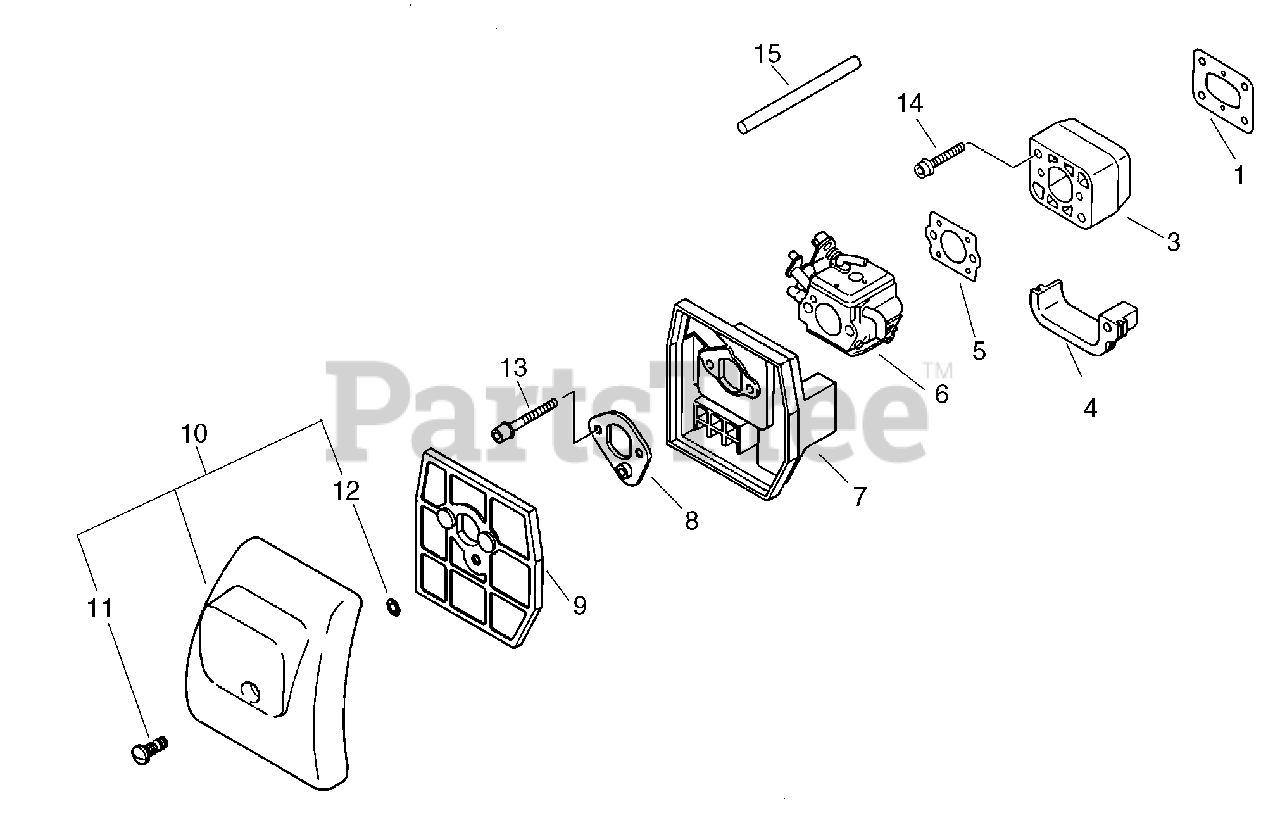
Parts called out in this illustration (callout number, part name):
1	GASKET, INTAKE
3	INSULATOR
5	GASKET, INTAKE
6	CARBURETOR CLS-5800 SERIES
7	CASE, AIR FILTER
8	BRACKET, AIR FILTER
9	FILTER, AIR
10	AIR FILTER COVER ASSY
13	BOLT 5×55
14	BOLT 5×30
15	PIPE, FUEL 3×6×105 BLACK
